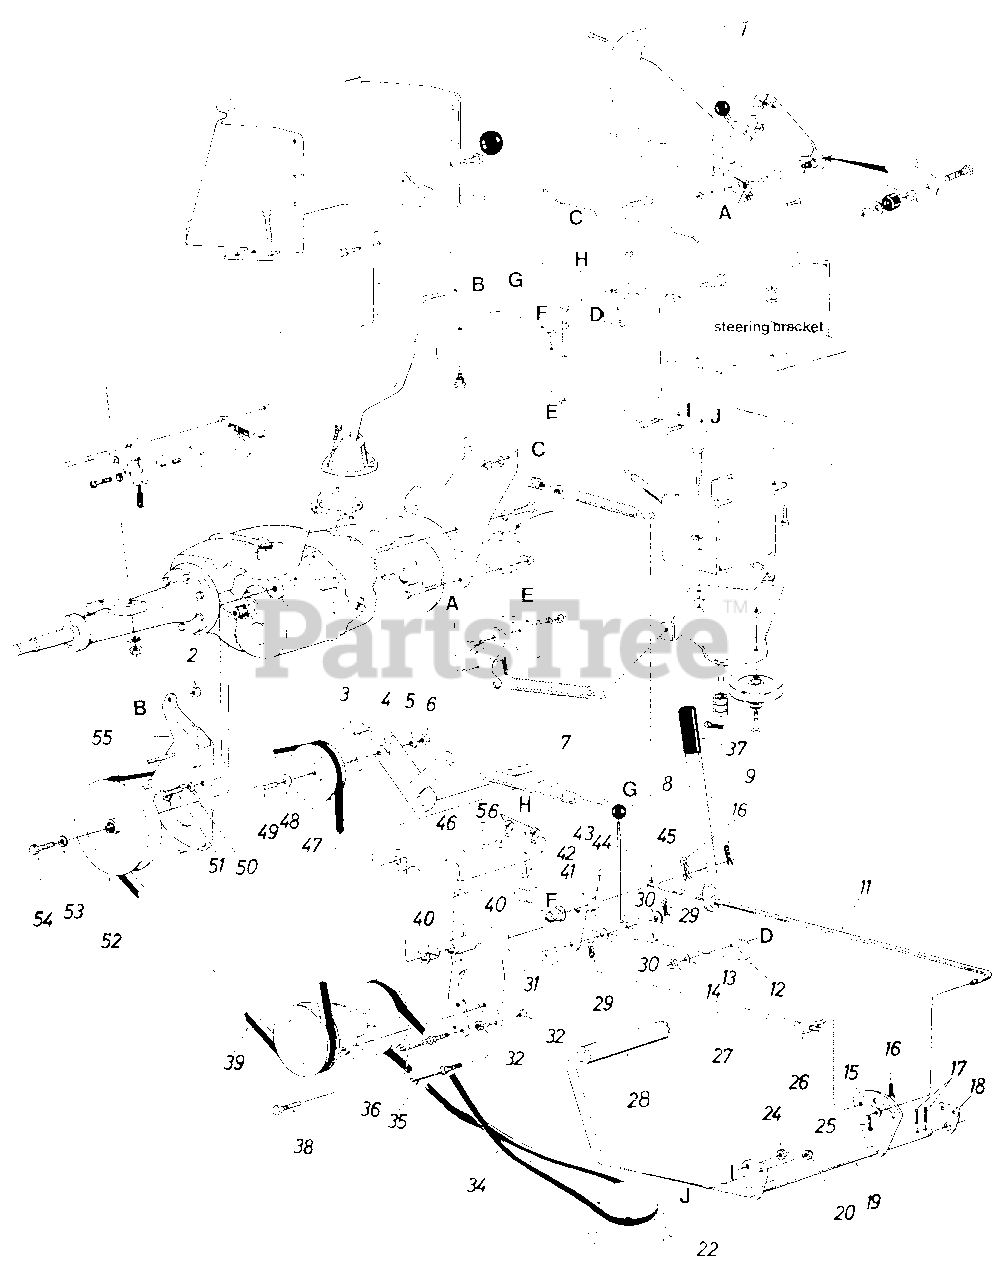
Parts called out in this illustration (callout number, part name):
2	Hex L-Nut 3/8-16 Thd.
5	L-Wash. 3/8" I.D.
6	Hex Nut 3/8-16 Thd.
7	Ext. Spring (Drive Idler)
8	Knob (Parking Brake)
9	Hand Brake Lever
9	Hairpin Cotter 3/8" Rod
11	Brake Rod
12	Parking Brake Cam
13	L.Wash. 5/16" I.D.
14	Hex Nut 5/16-18 Thd.
15	Fl-Wash. 5/16" I.D.
16	Hairpin Cotter 3/8" Rod
17	Cotter Pin 1/8" Dia. x 1.00" Lg.
18	Clutch Rod Brg. Brkt.
19	Clutch-Brake Pedal Ass'y.
20	Hex Cent. L-Nut 3/8-16 Thd.
22	Engine Pulley 4.75 & 5.56
24	Hex Cent. L-Nut 3/8-16 Thd.
25	Cotter Pin 3/32" Dia. x .75" Lg.
26	Pivot Bushing
27	Brake Cam Rod
28	Foot Pad
29	Hairpin Cotter 3/8" Rod
30	Fl-Wash. 3/8" I.D. x 1.00" O.D. x .030
31	Jack Shaft Mtg. Brkt. Ass'y.
32	Hex Top L-Nut 3/8-16 Thd.
34	V-Belt
35	Stud 3/8-16 x 3.62" Lg. Special
36	Jack Shaft Ass'y.
37	Flat Grip
38	Hex Sem Scr. 5/16-18 x .75" Lg.
39	V-Belt
40	Nyliner 5/8" I.D. x .88" Lg.
41	Ext. Spring (Jack Shaft)
42	Hex Thd. Rolling Scr. 1/4-20 x.50" Lg.
43	Clutch-ldler Horn Ass'y.
44	Spring Pin Spiral 1/4" Dia. x 1.00" Lg.
45	Parking Brake Link
46	Idler Mtg. Brkt.-Drive
47	4" "V"-ldler Pulley
48	Fl-Wash. 3/8" I.D.
49	Hex Bolt 3/8-16 x 1.75" Lg.
50	L-Wash. 3/8" I.D.
51	Hex Bolt 3/8-16 x .75" Lg.
52	V-Pulley 7.0" O.D. (Transaxle)
53	L-Wash. 3/8" l.D.
54	Hex Scr. 3/8-24 x .75" Lg.
55	Belt Guard Ass'y.
56	Plastic Hose Clamp
